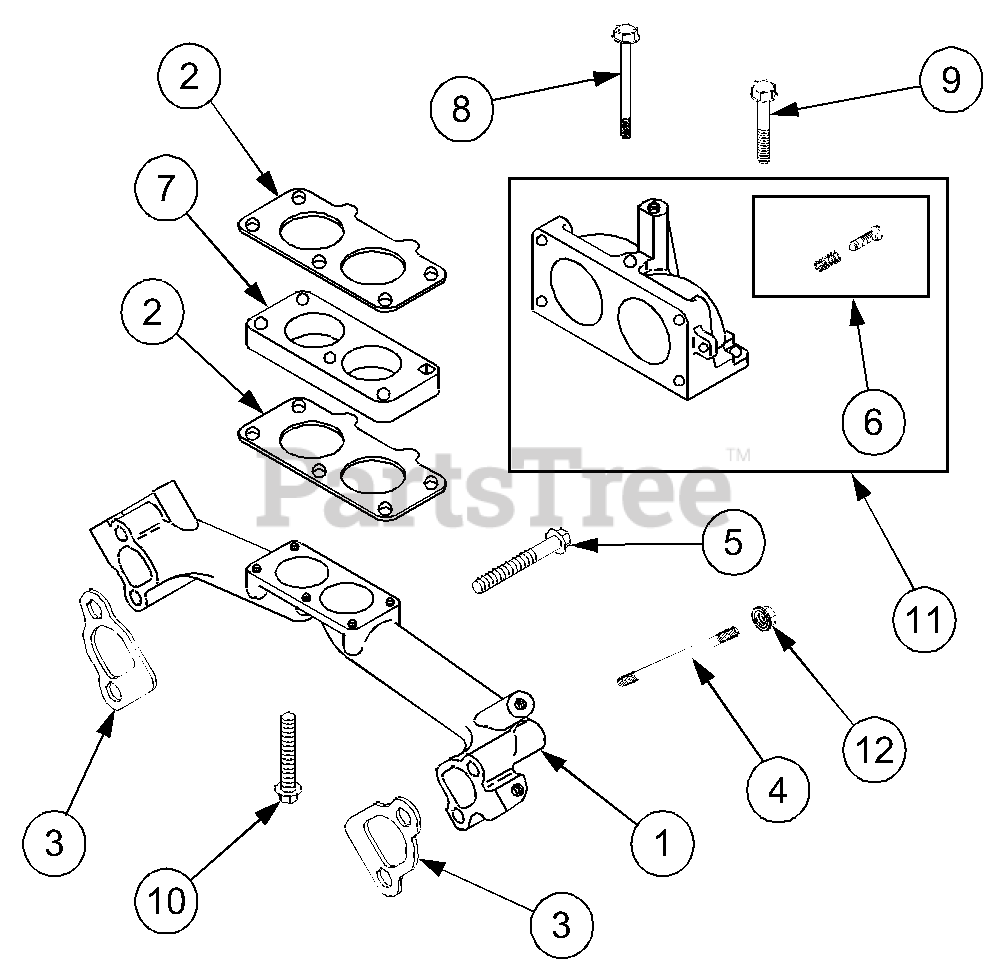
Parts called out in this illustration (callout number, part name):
1	Manifold, Intake
2	Gasket, Intake Manifold
3	Gasket, Intake Manifold
4	Stud, Carburetor
5	Screw, Intake Manifold
6	Kit, Idle Speed
7	Spacer, Carburetor
8	Screw, Intake Elbow
9	Screw, Intake Elbow
10	Screw, Carburetor
11	Elbow, Intake
12	Nut, Carburetor
